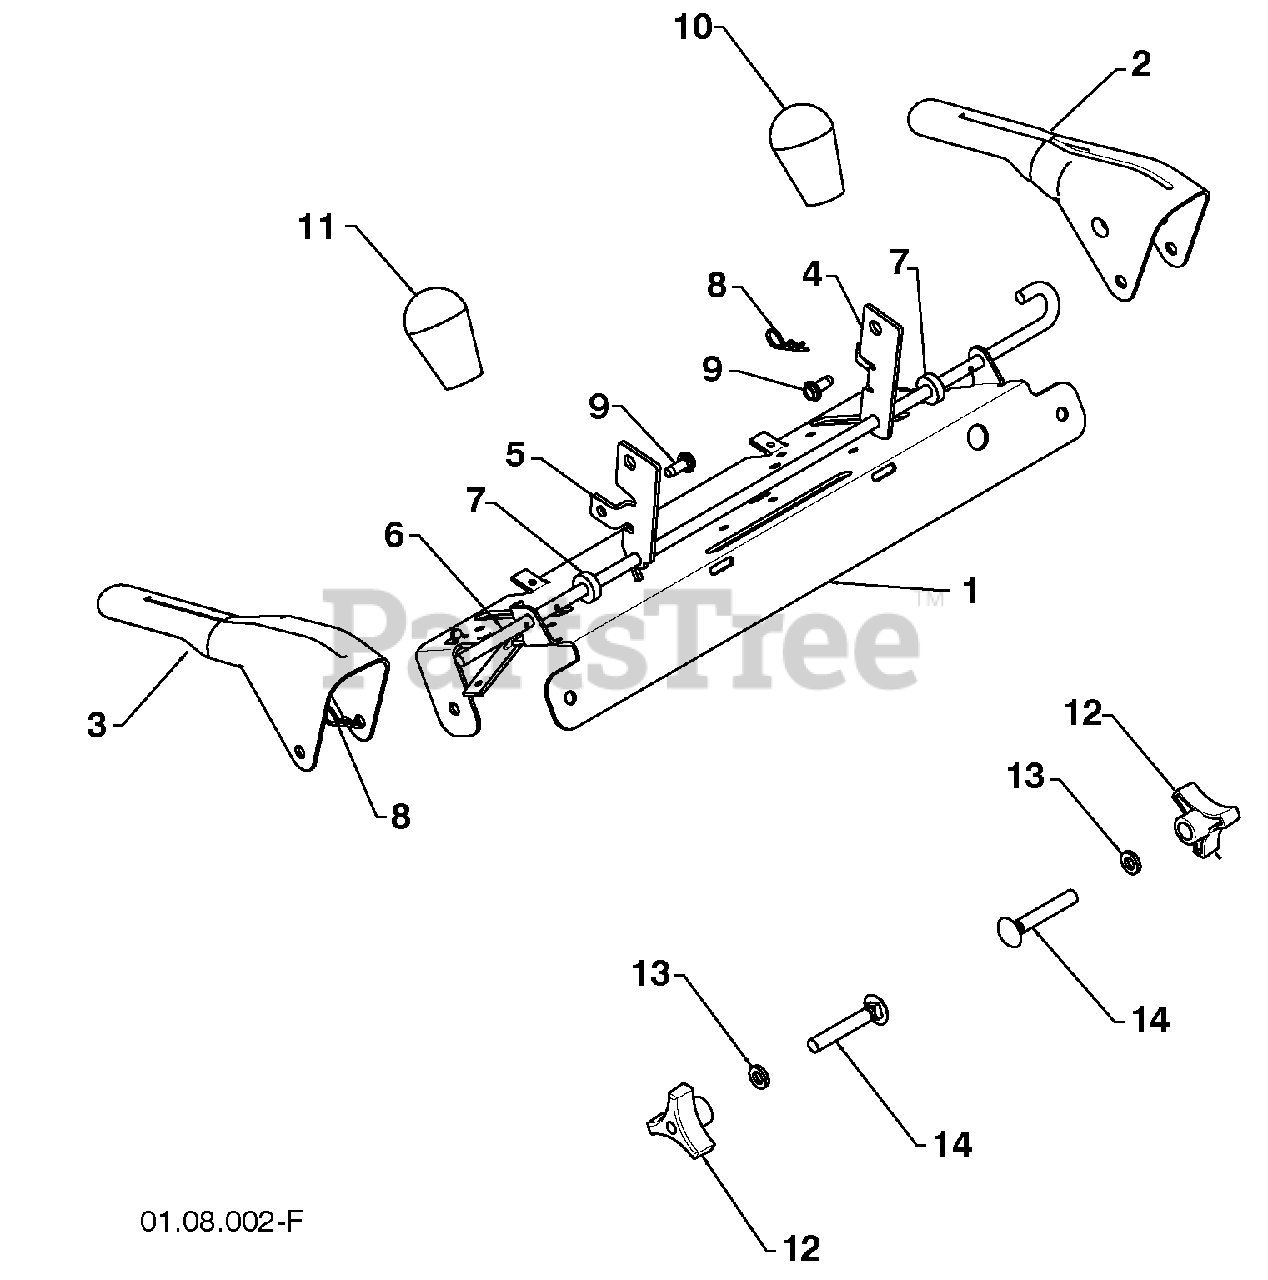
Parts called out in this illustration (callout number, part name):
1	CONTROL PANEL
2	CONTROL LEVER LH
3	CONTROL LEVER RH
4	TRACTION ROD ARM
5	IMPELLER ROD ARM
6	INTERLOCK BAIL
8	RETAINER
9	SCREW 1/4-20 X .62
10	KNOB BLACK
11	KNOB RED
12	HANDLE KNOB
13	WASHER 3/8
14	CARRIAGE BOLT 3/8-16 X 2.25
